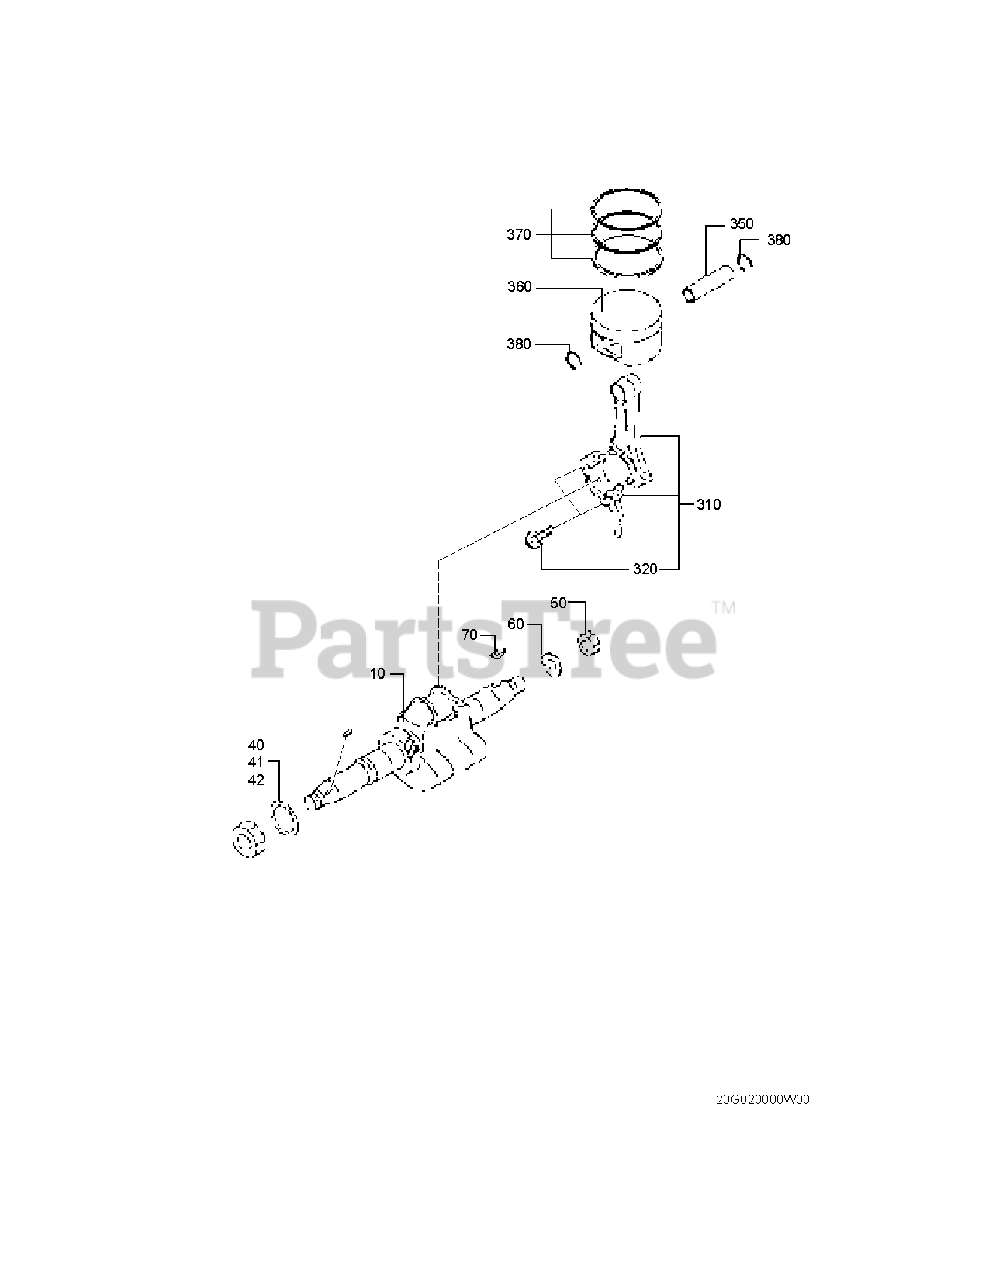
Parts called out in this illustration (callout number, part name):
310	CONNECTING ROD AY
320	CONNECTING ROD BOLT
350	PISTON PIN
370	PISTON RING SET
